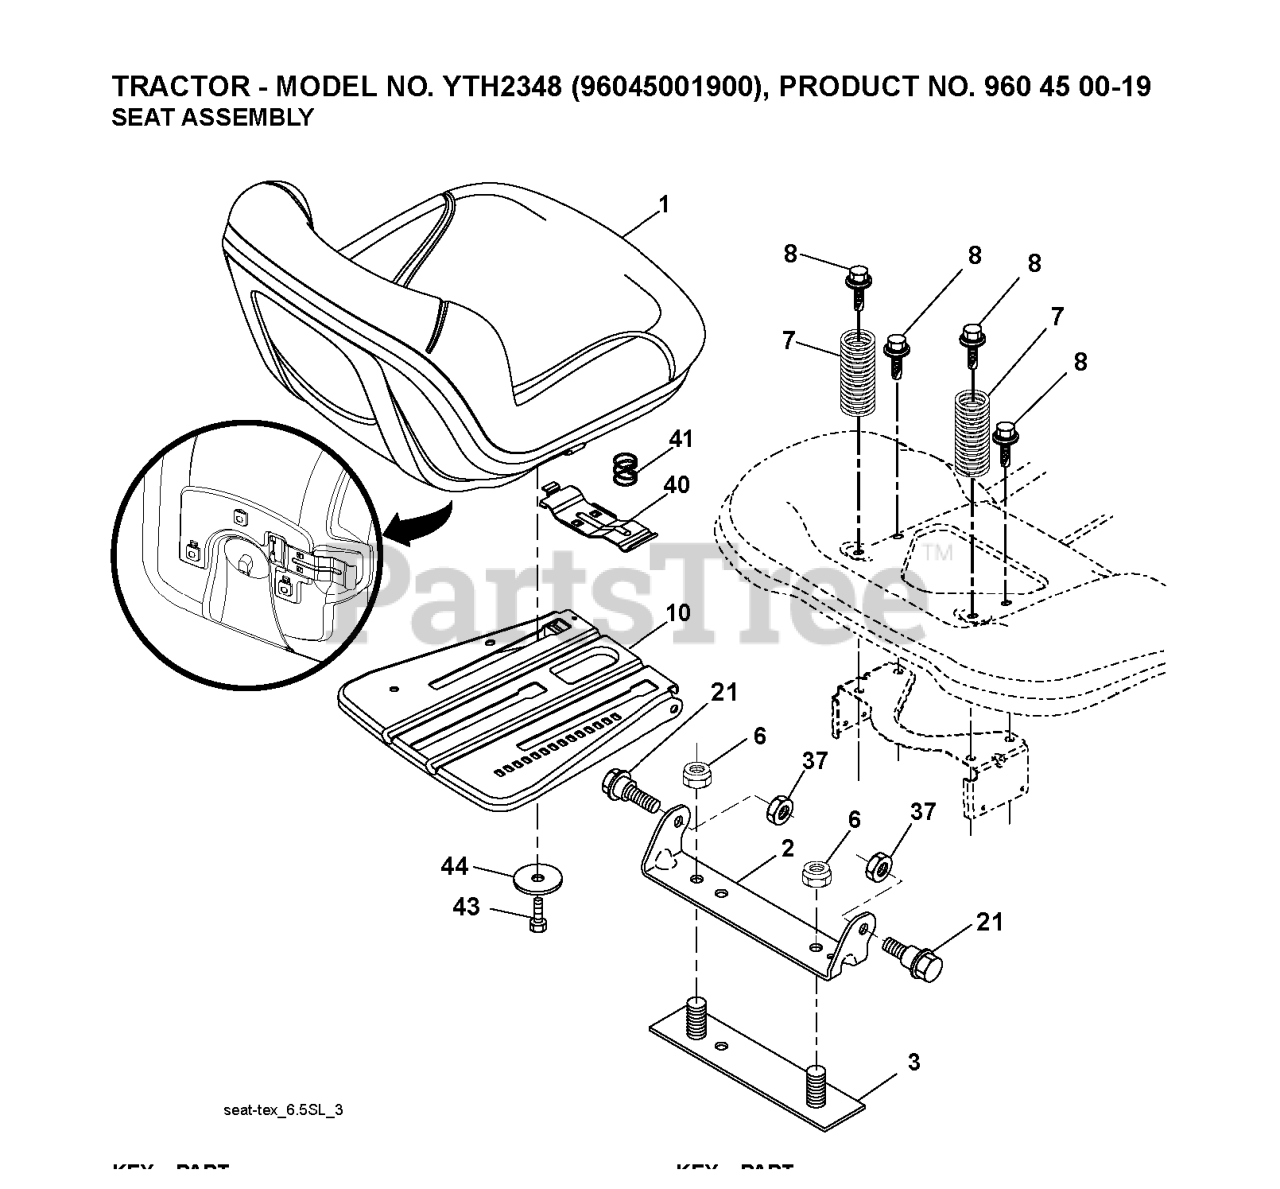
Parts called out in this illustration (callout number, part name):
1	SEAT - GREY
2	BRKT.PIVOT.FENDER
3	STRAP
6	NUT
7	SPRING COMPRESSION
8	BOLT.5/16-18UNCX3/4 W/SEMS.BLK
10	PAN.ASM.SEAT.3PT
21	BOLT.SHOULDER.5/16-18
37	NUT.71038.31-18.HEX.NYLOCK
40	HANDLE.SLIDE.SEAT.TEX.BLACK
41	SPRING.LATCH.SEAT.TEX
44	WASHER 13/32 X 2-3/8 X 12GA
